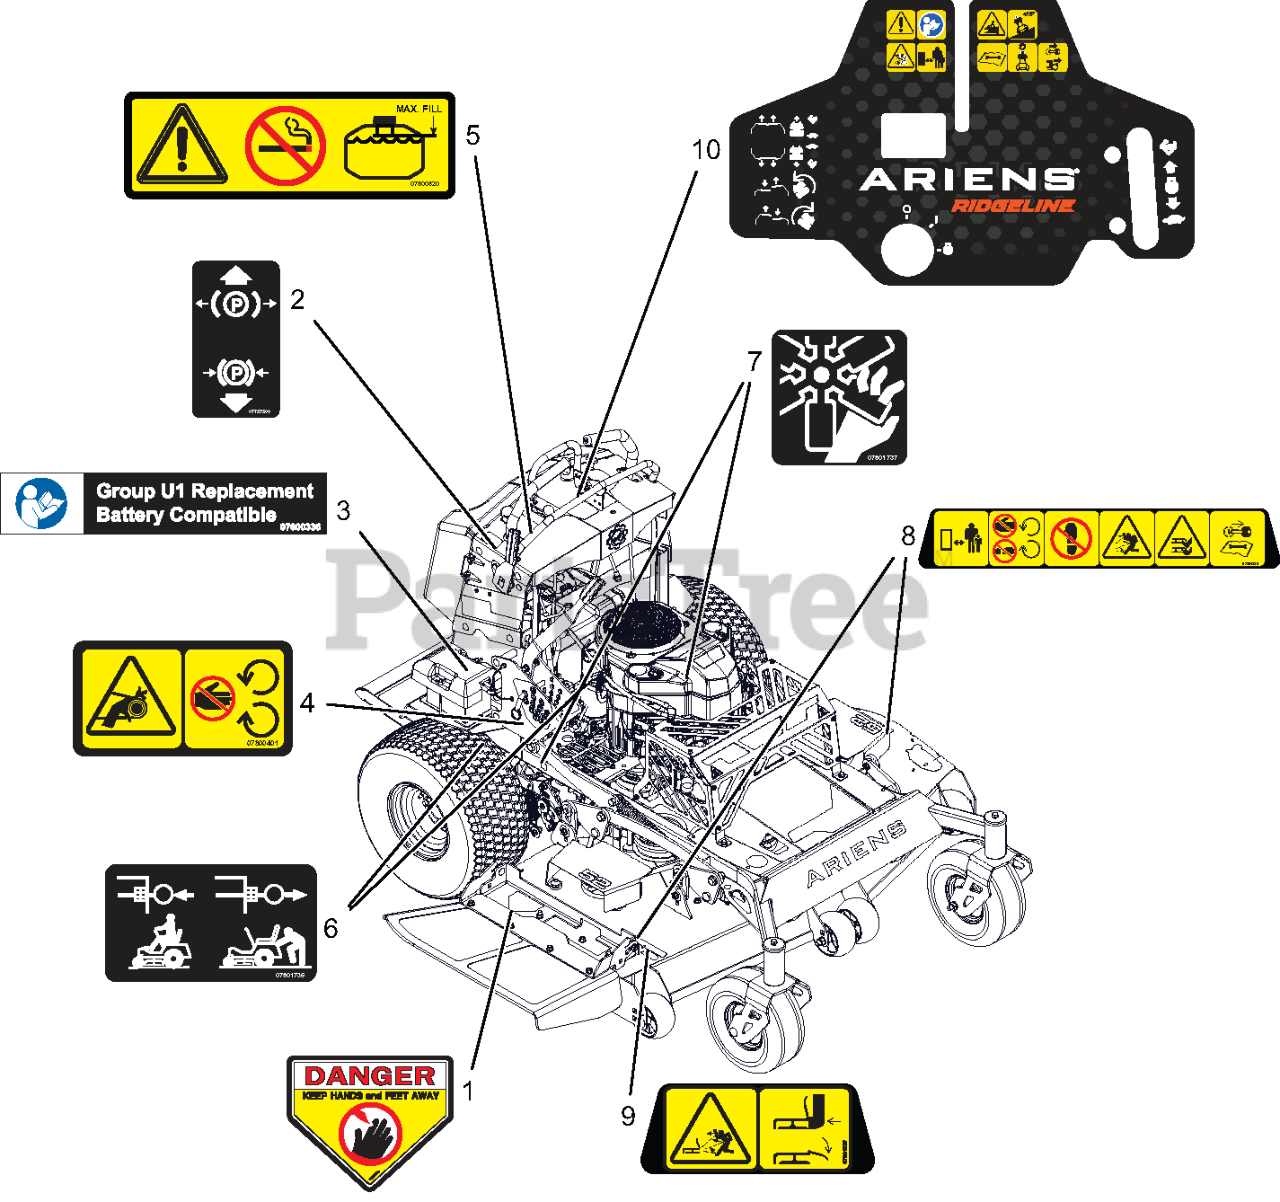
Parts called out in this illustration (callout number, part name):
1	DECAL, DANGER
2	DECAL, PARKING BRAKE LEVER
3	DECAL, U1 BATTERY REPLACEMENT
4	DECAL, SAFETY - GUARDING
5	DECAL, FUEL WARNING
6	DECAL- TRANSAXLE DISCONNECT
7	DECAL- DANGER FAN
8	DECAL- SAFETY - MOWER DECK
9	DECAL- SAFETY - DECK GUARDING
10	DECAL- DASH
